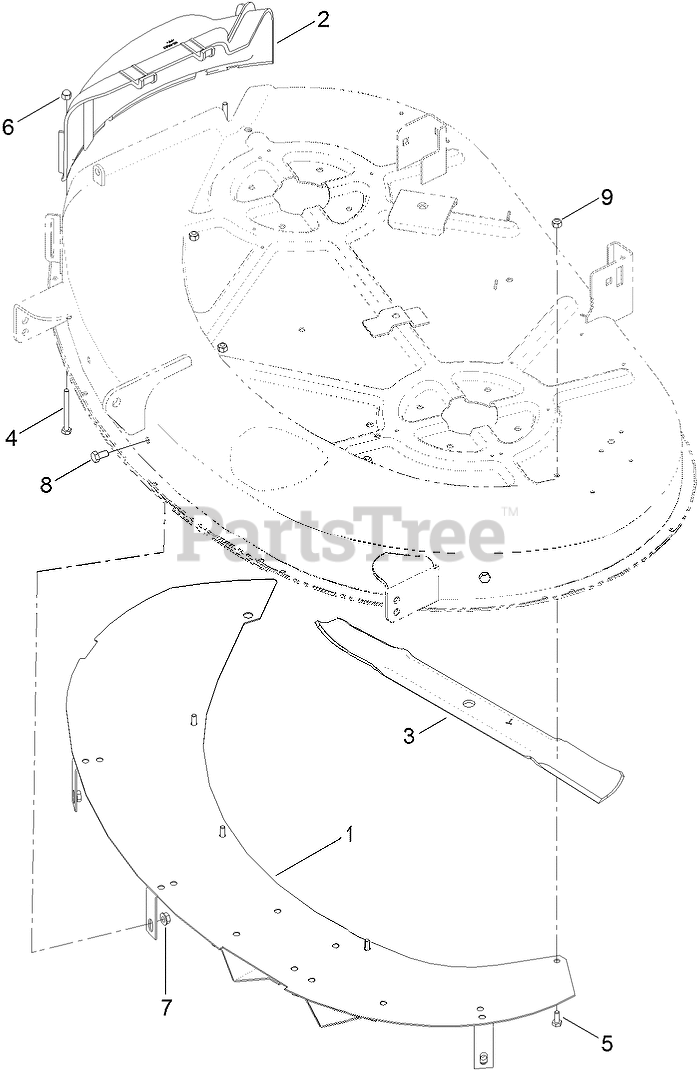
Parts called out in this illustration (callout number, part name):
1	BAFFLE UPPER ASM
2	COVER-DISCHARGE
4	SCREW-HH
5	SCREW-HH
6	NUT-CAP
7	NUT-HF
8	SCREW-HH
9	NUT-LOCK, NI
